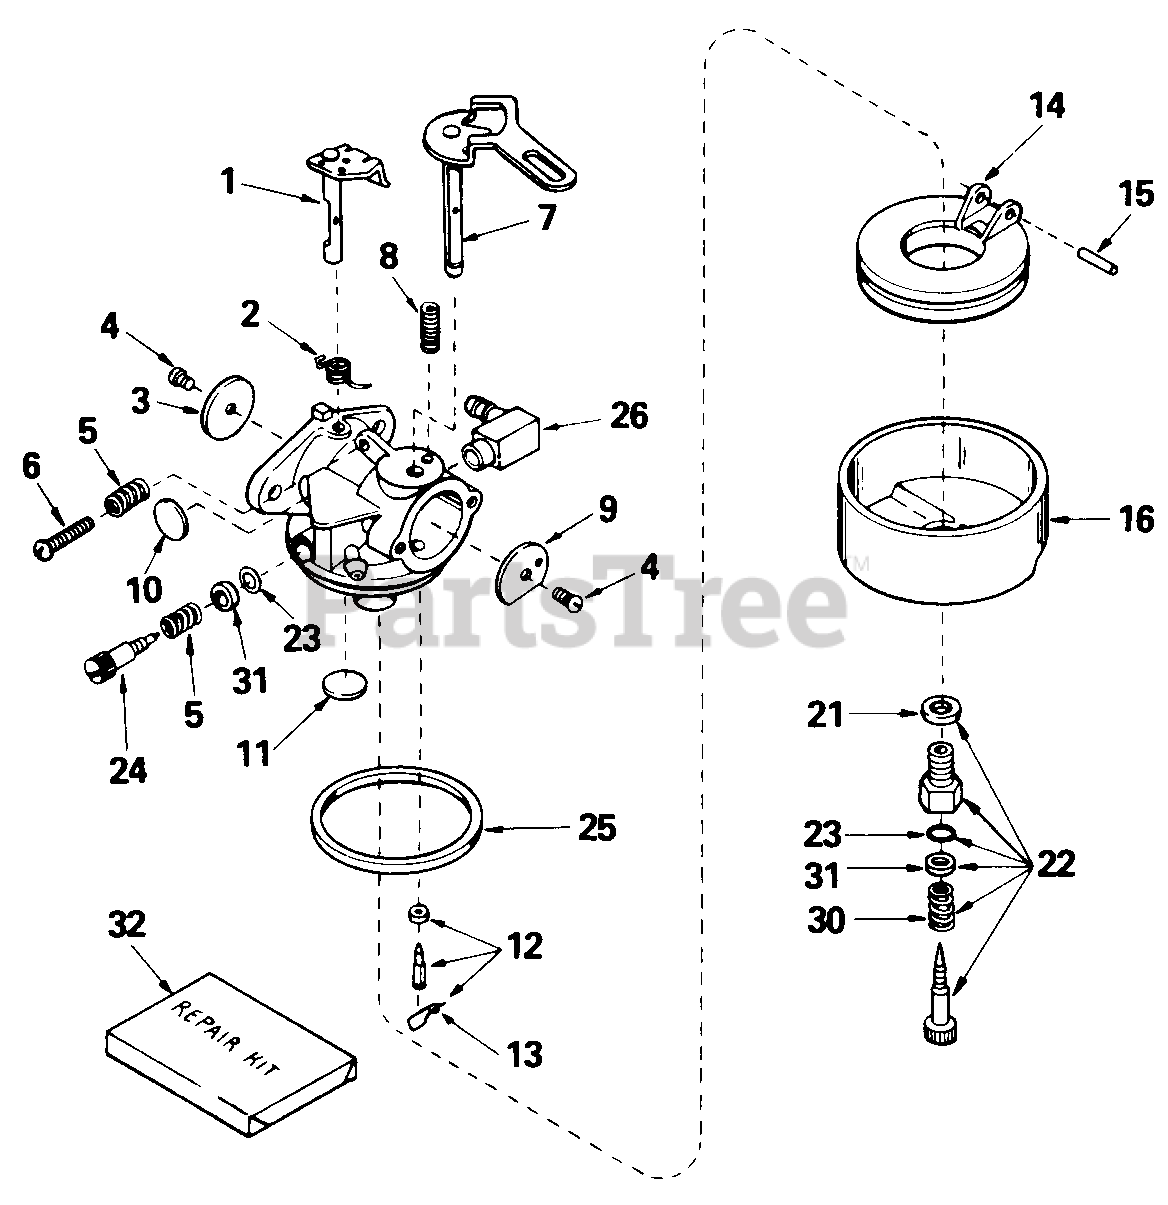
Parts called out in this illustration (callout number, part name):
1	Shaft & Lever Ass'y., Throttle
2	Spring, Throttle Return
3	Shutter, Throttle
4	Screw, 4-40 x 3/16
5	Spring, Idle Regulating Screw
6	Screw, Idle Regulating
7	Shaft & Lever Ass'y., Choke
8	Spring, Choke Stop
9	Shutter Choke
10	Plug, Welch
11	Plug, Welch
12	Inlet Needle, Seat & Clip Ass'y.
13	Clip, Inlet Needle
14	Float, Carburetor
15	Shaft, Float
16	Bowl, Float
21	Gasket, Bowl-to-Body
22	Adjustment Screw Ass'y., Main
23	"O"-Ring, Adjustment Screw
24	Screw, Idle Adjustment
25	Gasket, Bowl-to-Body
26	Fitting, Fuel Inlet
30	Spring, Main Adjustment Screw
31	Washer, Flat
32	Repair Kit
